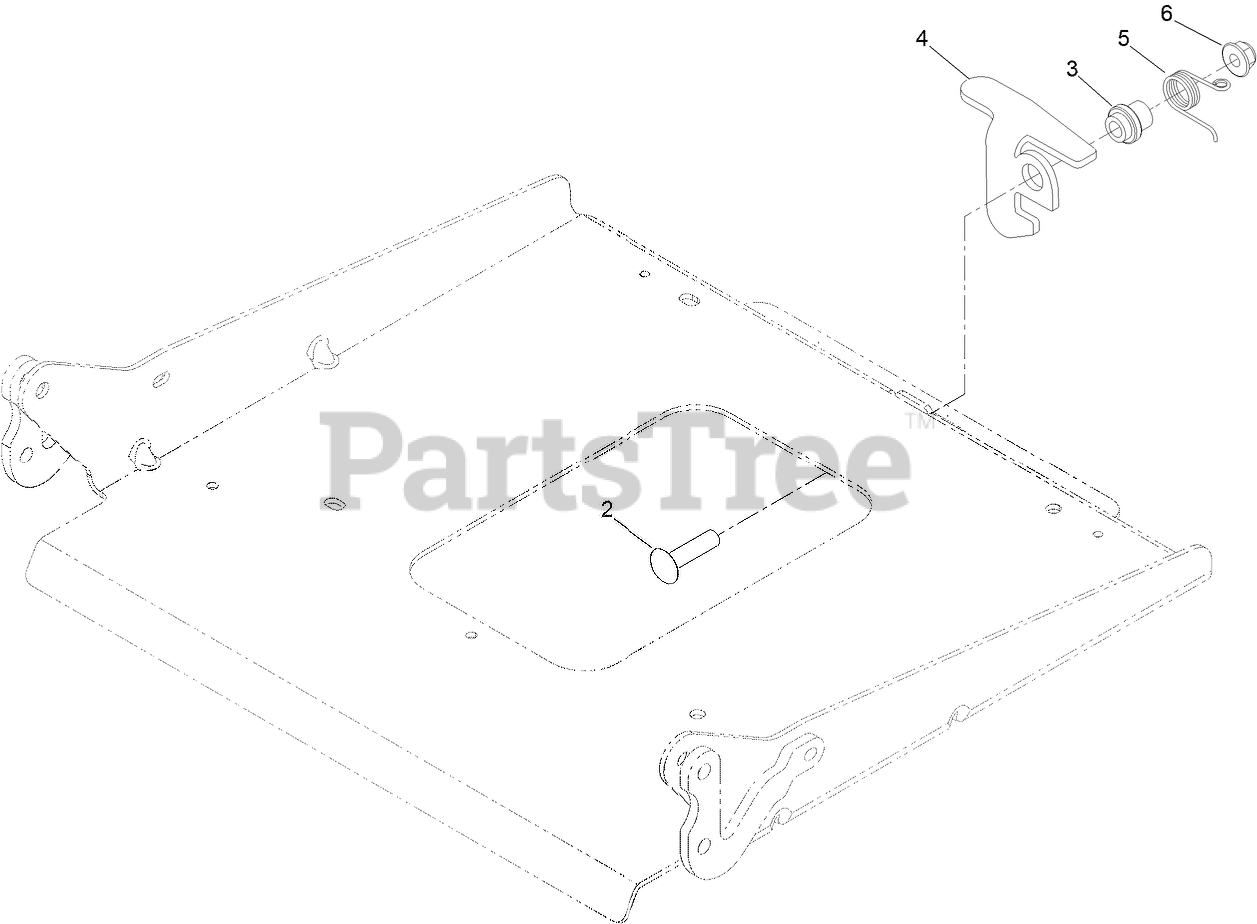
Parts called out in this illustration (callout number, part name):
2	SCREW-CARR
3	BUSHING-LATCH, SEAT
4	LATCH-CATCH, SINGLE
5	SPRING-TORSION, LATCH
6	NUT-HF, NI
